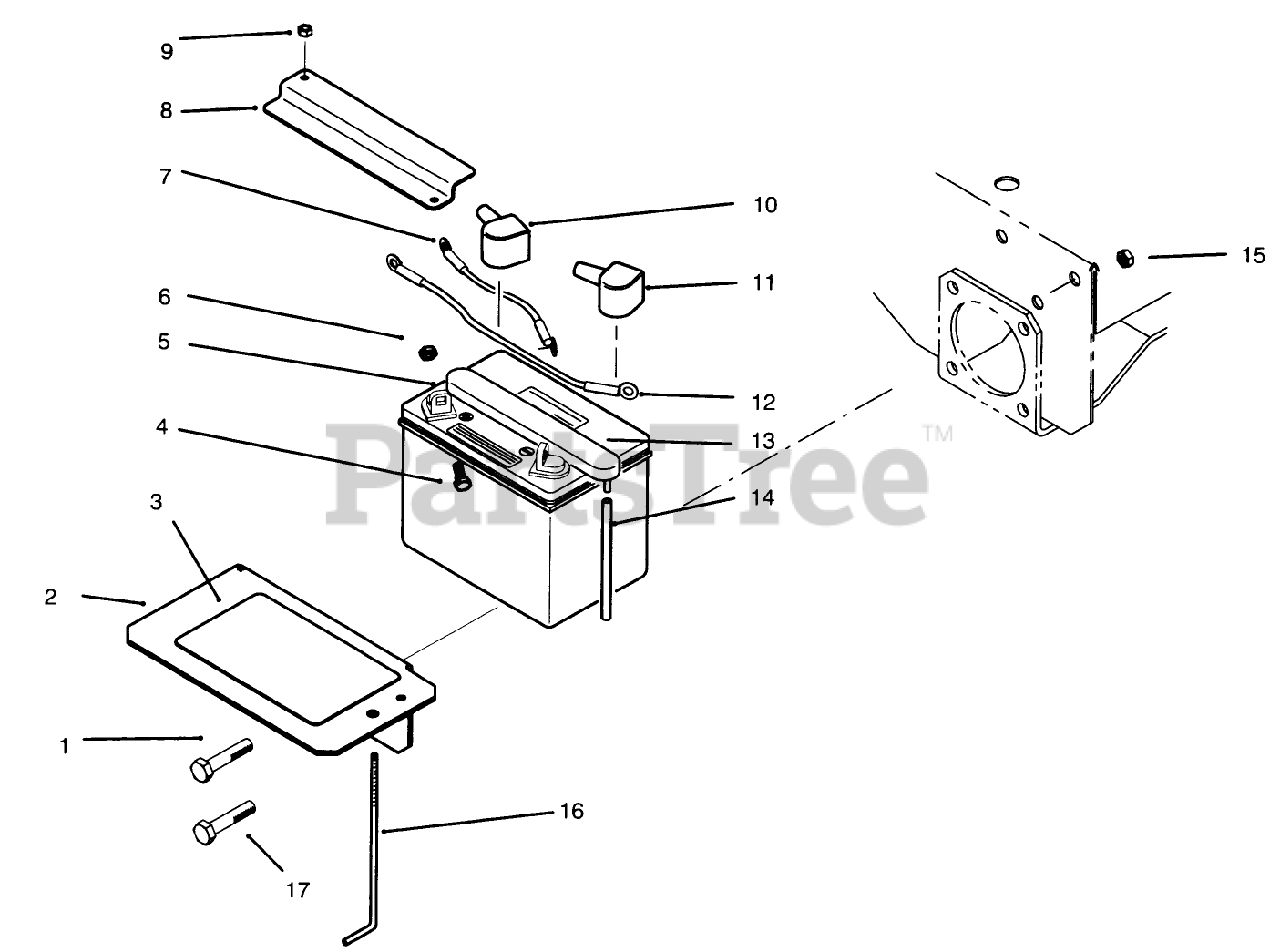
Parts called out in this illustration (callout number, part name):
1	SCREW-HHF
2	Holder-Battery
3	PAD-SKID, ANTI
4	SCREW-HH
5	Battery
6	NUT-KEPS
7	WIRE ASM
8	Clamp-Battery
9	NUT-LOCK, NI
10	BOOT-TERMINAL, BLACK
11	BOOT-TERMINAL, RED
12	WIRE-SOLENOID/STARTER
14	TUBE-VENT
15	NUT-HF
16	ROD-SUPPORT, BATTERY
17	SCREW-HHF
